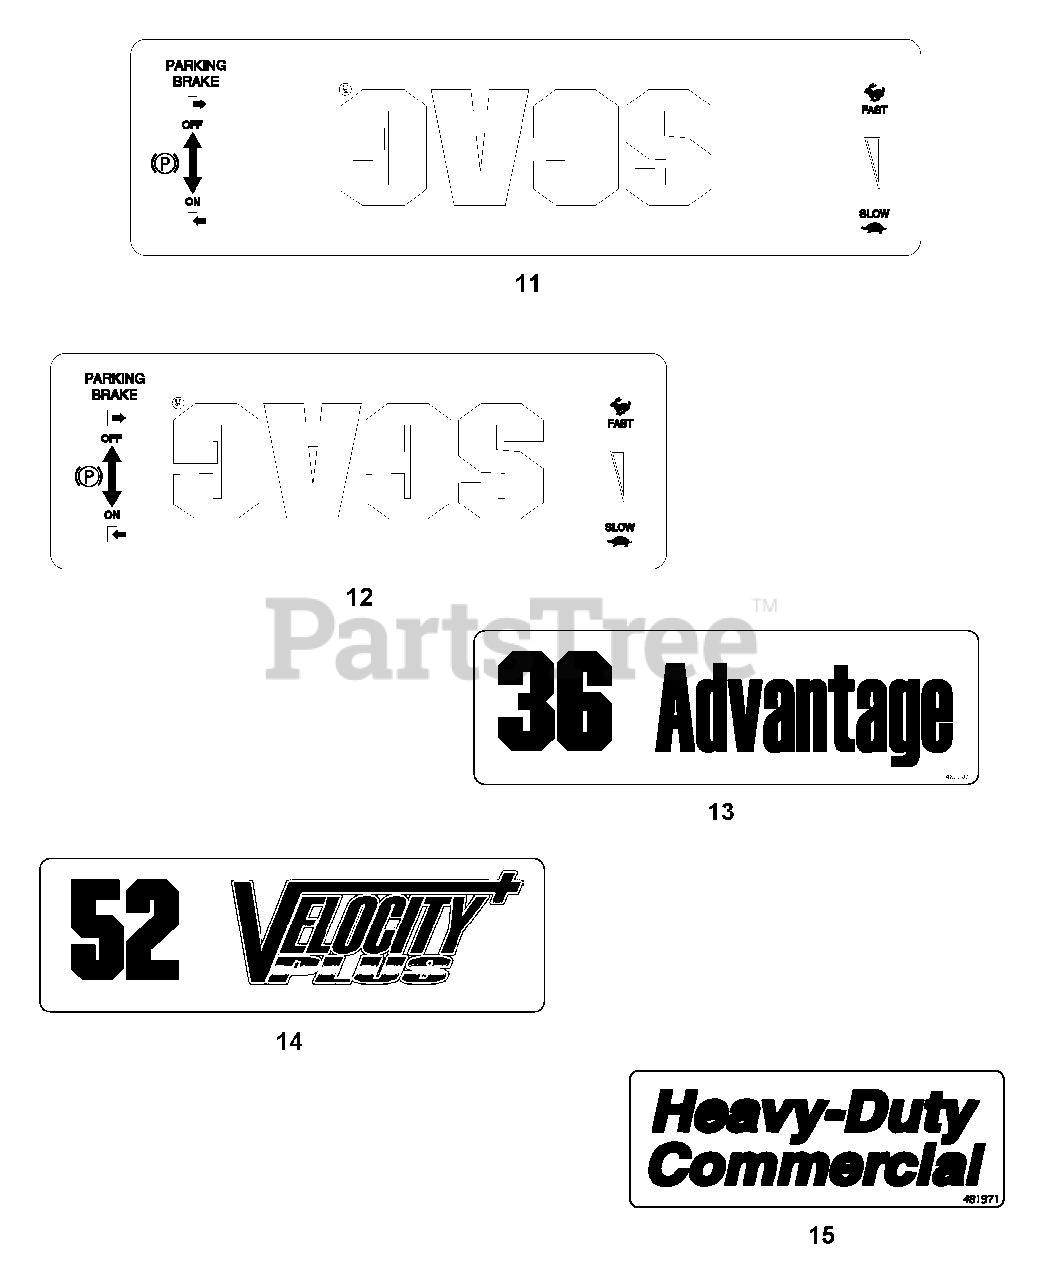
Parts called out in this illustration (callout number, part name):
11	Decal, Instrument Panel - Front
12	Decal, Instrument Panel - Front
13	Decal, 36 Advantage
14	Decal, 48 Velocity Plus
15	Decal, Heavy Duty Commercial
